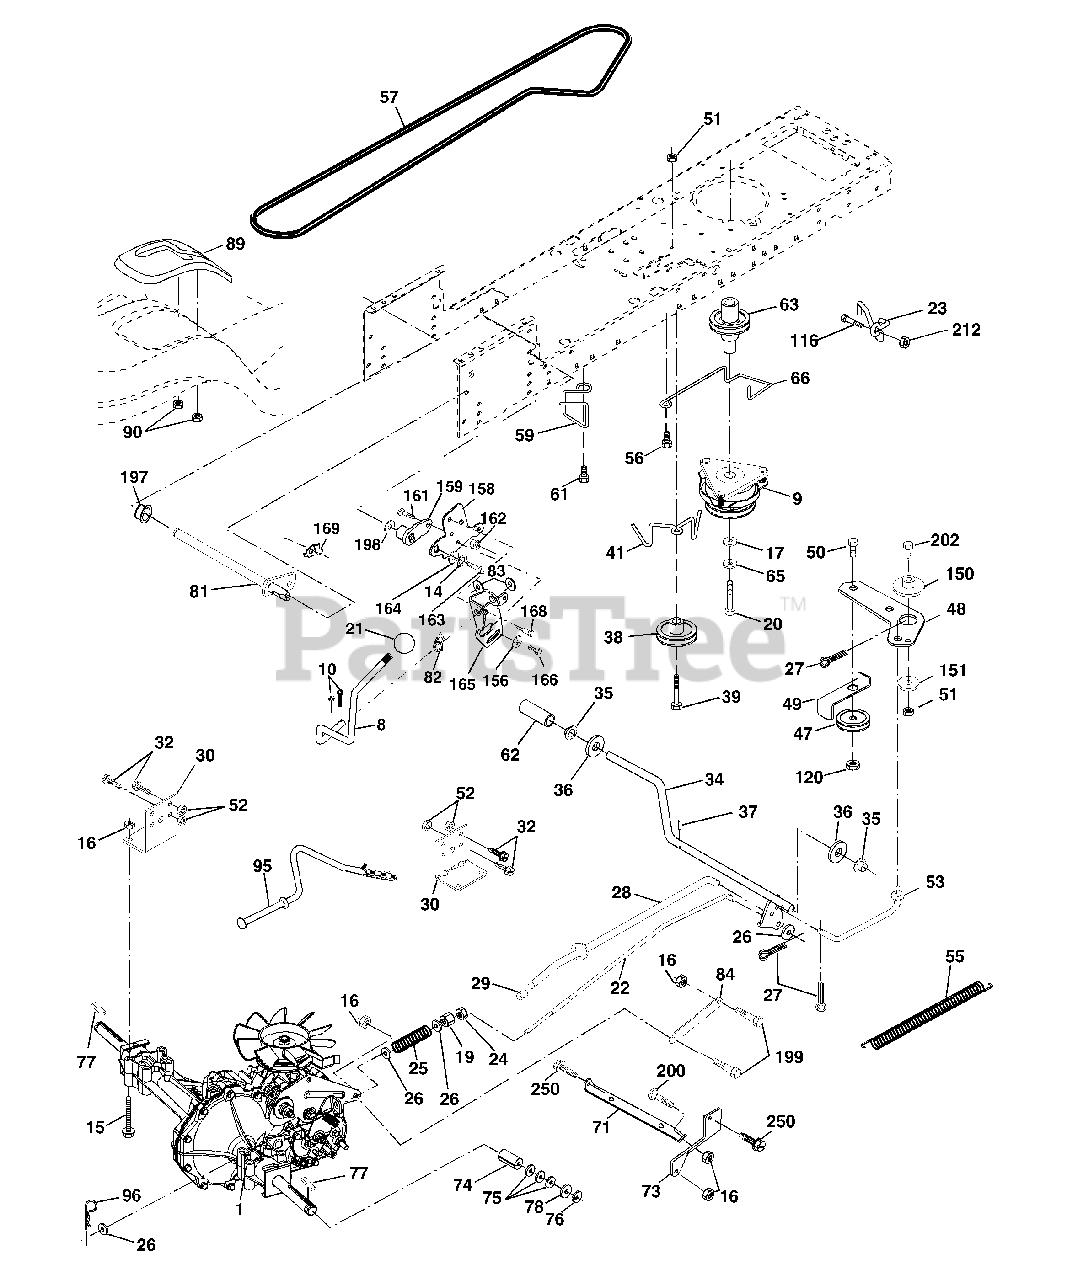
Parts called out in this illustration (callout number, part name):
8	Rod Shift Fender Adjust STLT
9	Clutch Elecric
10	Pin Cotter 1/8 x 1 CAD
14	Washer Lock Hvy Helical
15	Bolt Hex 5/16-18 Unc Flghd
16	Nut Lock Hex W/Ins. 5/16-18 Unc P
19	Nut Lock Hex W/Ins 3/8-16 Unc
20	Bolt, Hex 7/16-20 x 4-1/4 Ga. 5
21	Knob Deluxe 1/2-13 UNC BLK/BLK
22	Rod, Brake Hydro
23	Bracket Asm Mtg CL
24	Nut Hex Jam 3/8-16 UNC
25	Spring, Brake Rod
26	Washer
27	Pin Cotter 1/8 x 3/4 CAD.
28	Rod, Parking Brake
29	Cap,Parking Brake
30	Bracket, Transaxle
32	Bolt Hex Hd 5/16-18 Unc x 3/4
34	Shaft, Foot Pedal
35	Bearing, Nylon
37	Pin, Roll
38	Pulley, Composite
39	Bolt, Fin, Hex 3/8-16 x 3
41	Keeper, Belt Idler
47	Pulley, Idler, V-Groove Plastic
48	Bellcrank Clutch Grnd Drv STL
49	Retainer, Belt Style Spring
50	Bolt Hex Hd 3/8-16 Unc x 1-1/2
52	Nut Crownlock 5/16-18
53	Link, Clutch
55	Spring, Return, Clutch
56	Screw 3/8-16 x 1-1/4
57	V-Belt, Ground Drive
59	Keeper, Center Span
61	Screw 3/8-16 x .875
62	Cover, Pedal
63	Pulley, Engine
65	Washer Lock Hvy HLCL Spr 7/16
66	Keeper Belt Engine
71	Strap Torque Lh Hydro
73	Strap Torque Rh Hydro
74	Spacer, Axle
75	Washer 25/32 x 1-1/4 x 16 Ga.
77	Key, Square
78	Washer 25/32 x 1-5/8 x 16 Ga
81	Shaft Asm Cross Tapered
82	Spring Torsion T/A
83	Washer 17/32 x 3/4 x 16 Ga.
84	Link Transaxle
89	Console, Shift
90	Nut Self Thd 1/4
95	Control Asm. Bypass Hydro
96	Retainer Spring 1" Zinc/Cad
116	Bolt Rdhd Sqnk 3/8-16 Unc x 1
120	Nut Lock Flg 3/8-16
150	Spacer Retainer
151	Washer 13/32 x 2 x 10 Ga.
156	Washer Srrted 5/16ID x 1.125
158	Bracket Shift Mount
159	Hub Tapered Flange Shift Lt
161	Bolt Rdhd Sqnk 1/4-20 x 3/4 Gr 5
162	Nut Crownlock 1/4-20 Unc
163	Bolt Hex Fin 1/4-20 Unc x 1 Gr 5
164	Washer 5/8 x .281 x 10 Ga
165	Bracket Pivot Lever
166	Screw 5/16-18 x 5/8
168	Bolt Shoulder 5/16-18 x .561
169	Plate Fastening STLT/CRD
172	Bushing 1.375 OD
197	Nyliner Snap 5/8" ID
198	Washer Nyl 7/8 ID x .105 Hyd
199	Bolt Shoulder 5/16-18 Unc
200	Bolt Rdhd Sqnk 5/16-18 Unc x 1
212	Nut Hex Flange Lock
250	Screw 3/8-16 x .75
